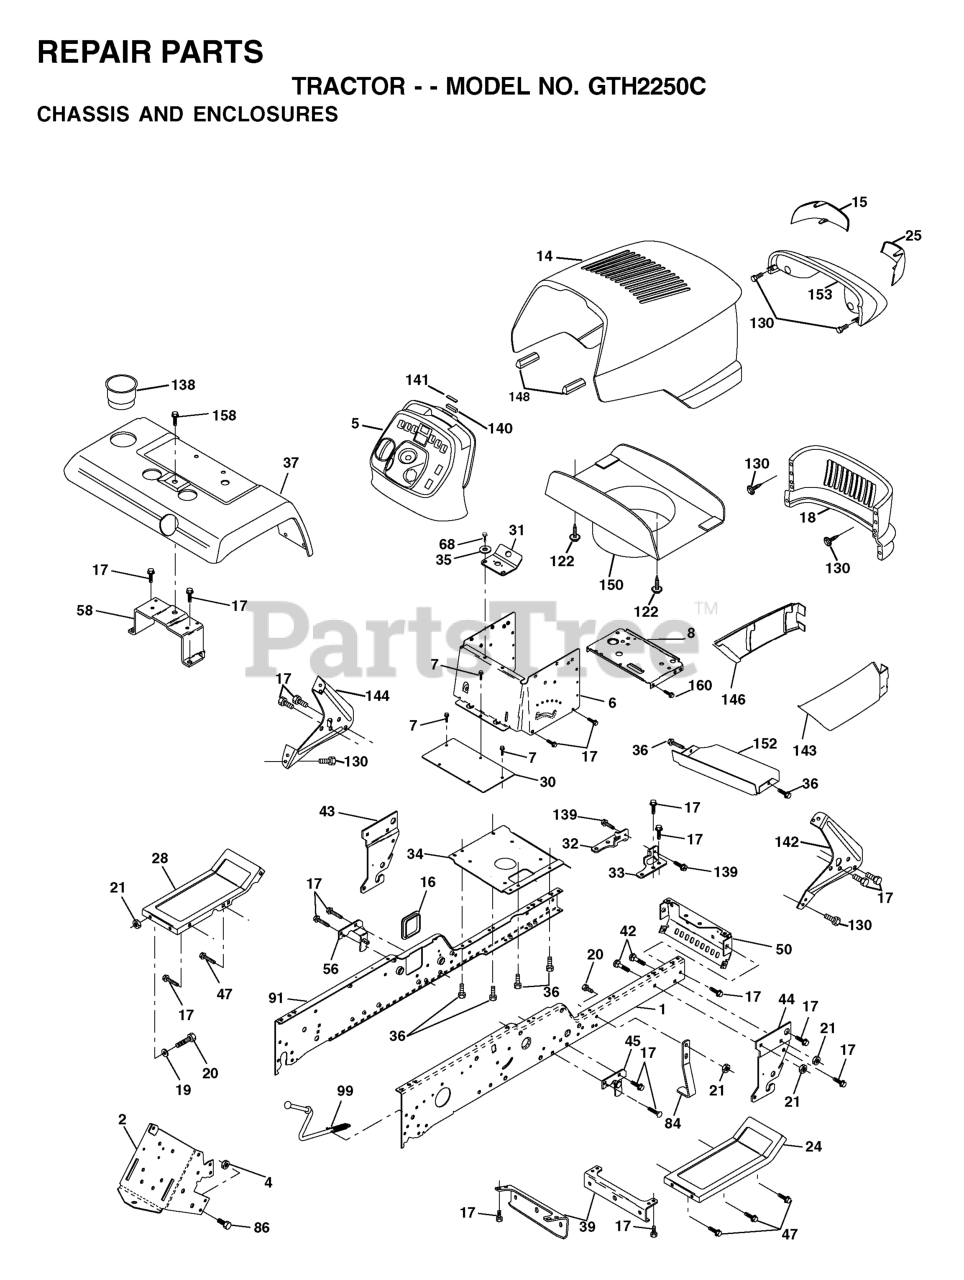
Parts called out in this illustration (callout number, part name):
821	MP BRACKET, WORM ADJ
822	DECAL, CONTROL PANEL ES
823	DECAL, CHOKE
824	DECAL, ST521E SIDE PANEL RH
825	DECAL, ST521E SIDE PANEL RH
826	DECAL, HUSQVARNA TOP COVER
827	DECAL, EPA
829	DECAL, START INSTR
830	DECAL, DANGER CHUTE
831	DECAL-DANGER AUGER/FOOT
832	DECAL, "CROWN" UPPRE CHT
833	Decal, Danger English
836	DECAL, AUGER CONTROL BAR
